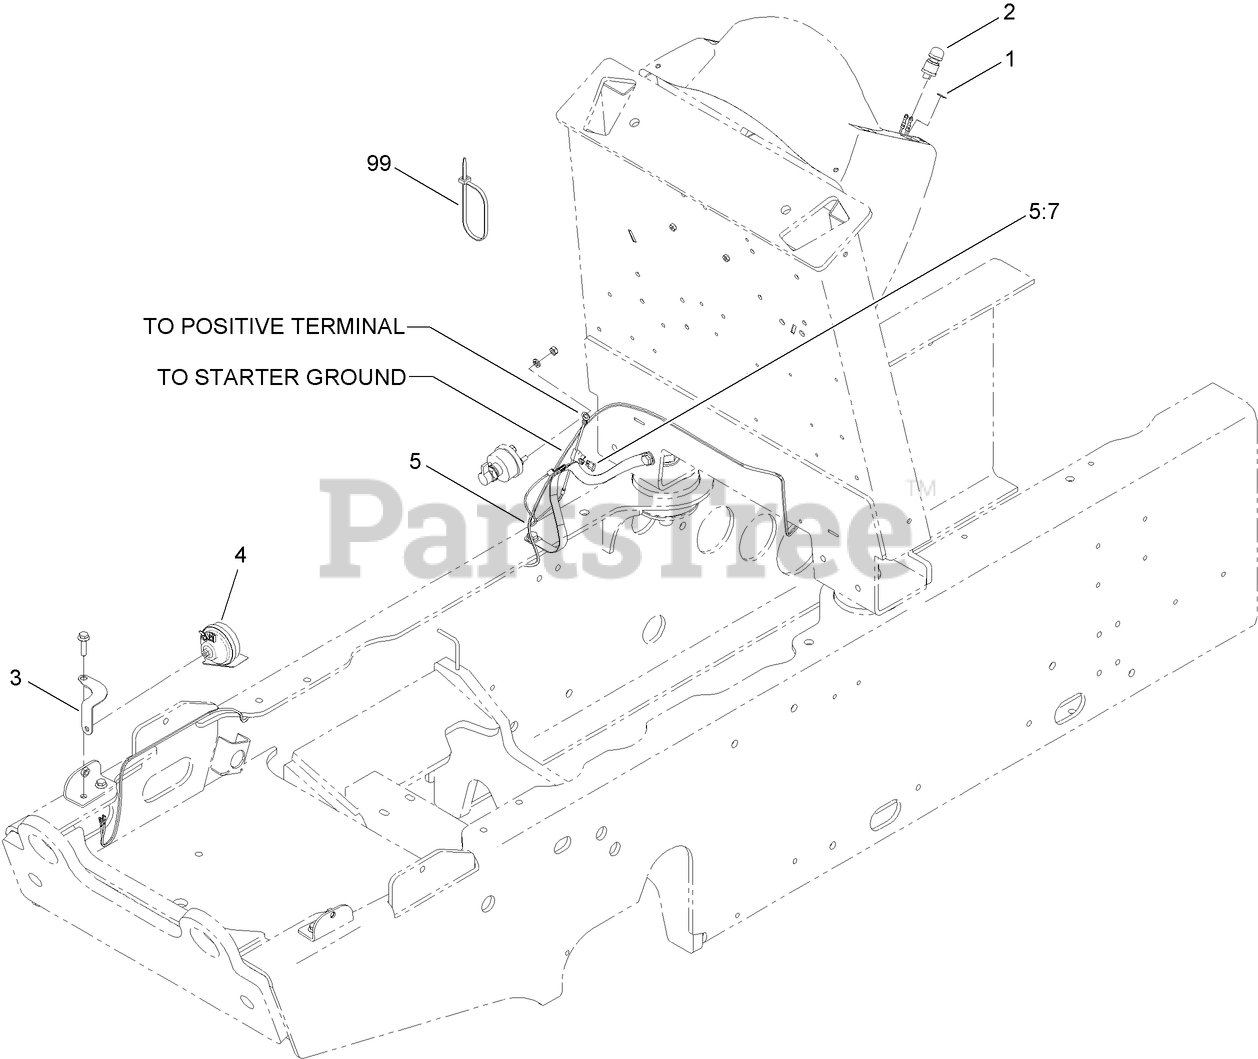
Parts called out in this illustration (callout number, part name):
1	Decal-Horn
2	SWITCH-PUSH BUTTON (SEALED)
3	BRACKET-MOUNTING, HORN
5	HARNESS-WIRE, HORN
5:7	FUSE-BLADE, 10 AMP
99	TIE-CABLE
